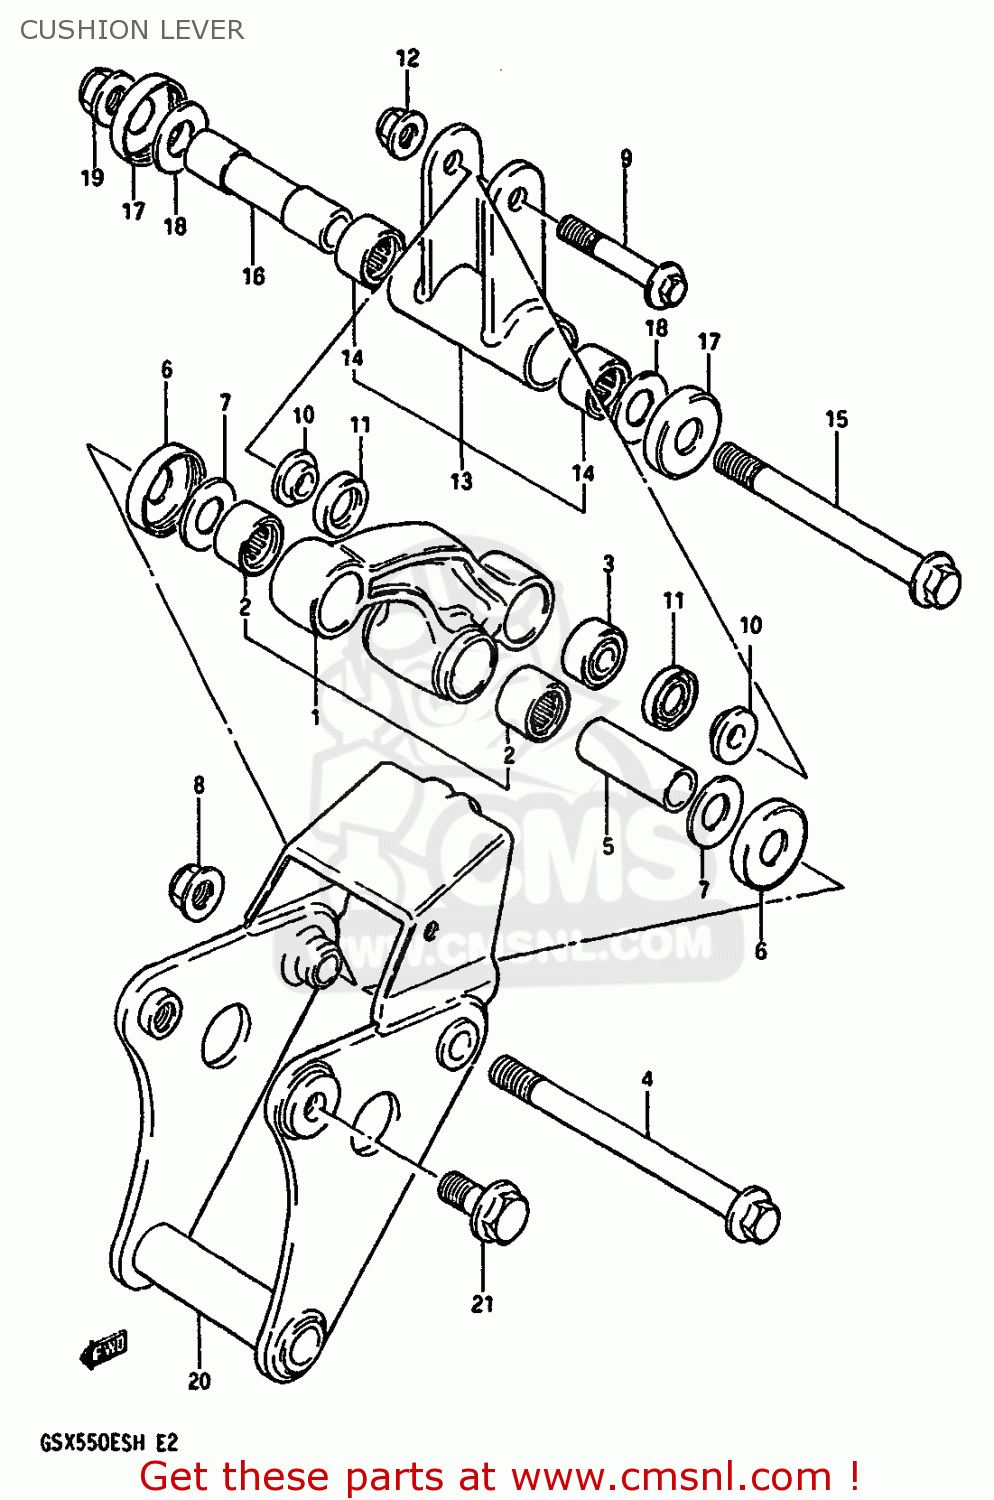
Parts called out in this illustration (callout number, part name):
1	LEVER SET,REAR CUSHION
2	ROLLER BEARING (17X24X2
3	BEARING(10X24X15)
4	SHAFT,REAR CUSHION LEVER
5	SPACER,REAR CUSHION LEVER
6	COVER,RR SWGARM DUST SEAL
7	WASHER
8	NUT 12MM
9	BOLT(10X52)
10	SPACER
11	DUST SEAL,RR CUSHION LEVER RR
12	NUT
13	LEVER SET,REAR CUSHION
14	ROLLER BEARING (17X24X2
15	BOLT,REAR CUSHION ROD
16	SPACER,REAR CUSHION ROD
17	COVER,RR SWGARM DUST SEAL
18	WASHER
19	NUT 12MM
20	HOLDER
21	BOLT(12X23)
